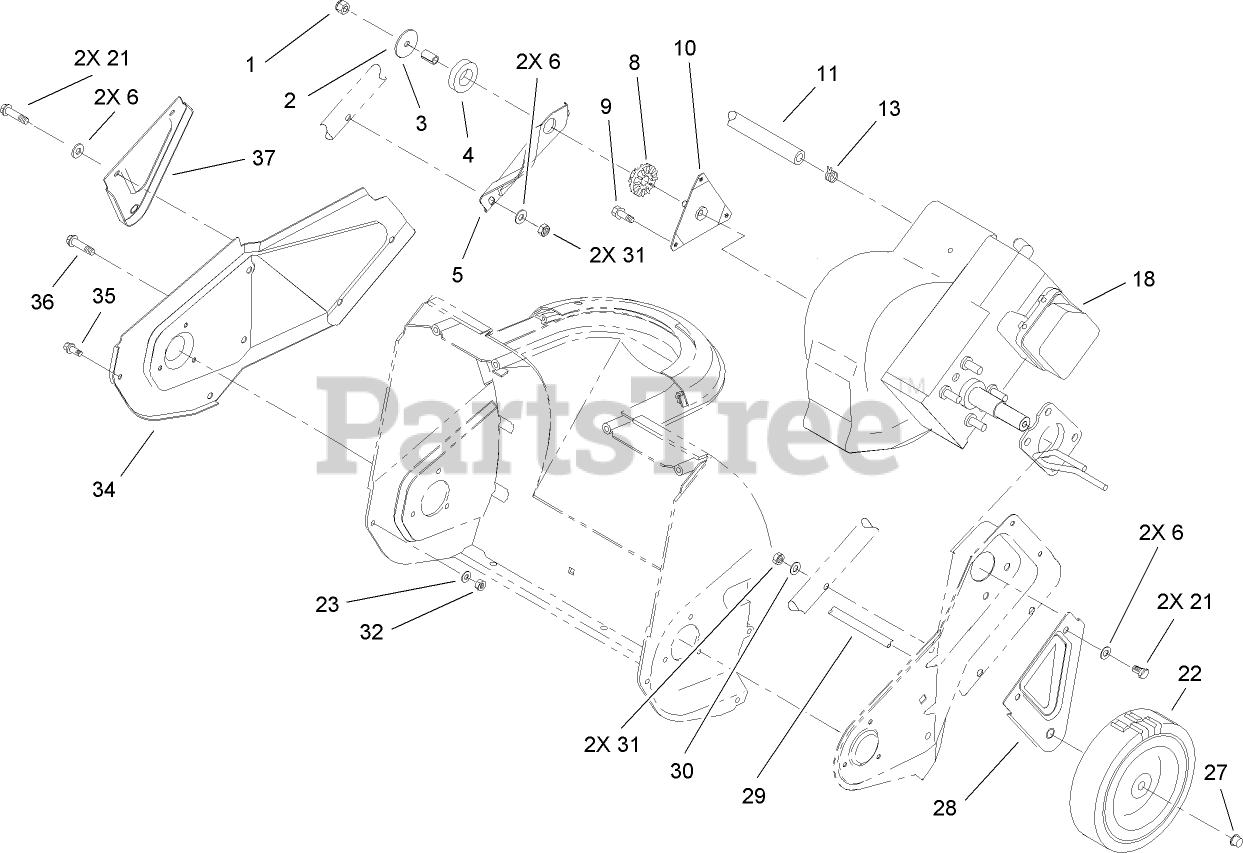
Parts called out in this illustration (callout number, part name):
1	NUT-LOCK, NI
3	SPACER-TUBULAR
4	RING-ISOLATOR
5	BRACKET-SUPPORT, ENGINE
6	WASHER-FLAT
8	BUSHING-ISOLATOR
9	SCREW
10	BRACKET AND STUD ASM
11	HOSE-FUEL
13	CLAMP-HOSE
18	Loose Parts Package
21	SCREW-HH
22	WHEEL
23	WASHER-FLAT
27	NUT-PUSH
28	BRACKET-WHEEL, LH
29	AXLE SHAFT
30	WASHER
31	NUT-LOCK, NI
32	NUT-LOCK, NI
34	PLATE-SIDE, RH
36	SCREW-PLASTIC
37	BRACKET-WHEEL, RH
